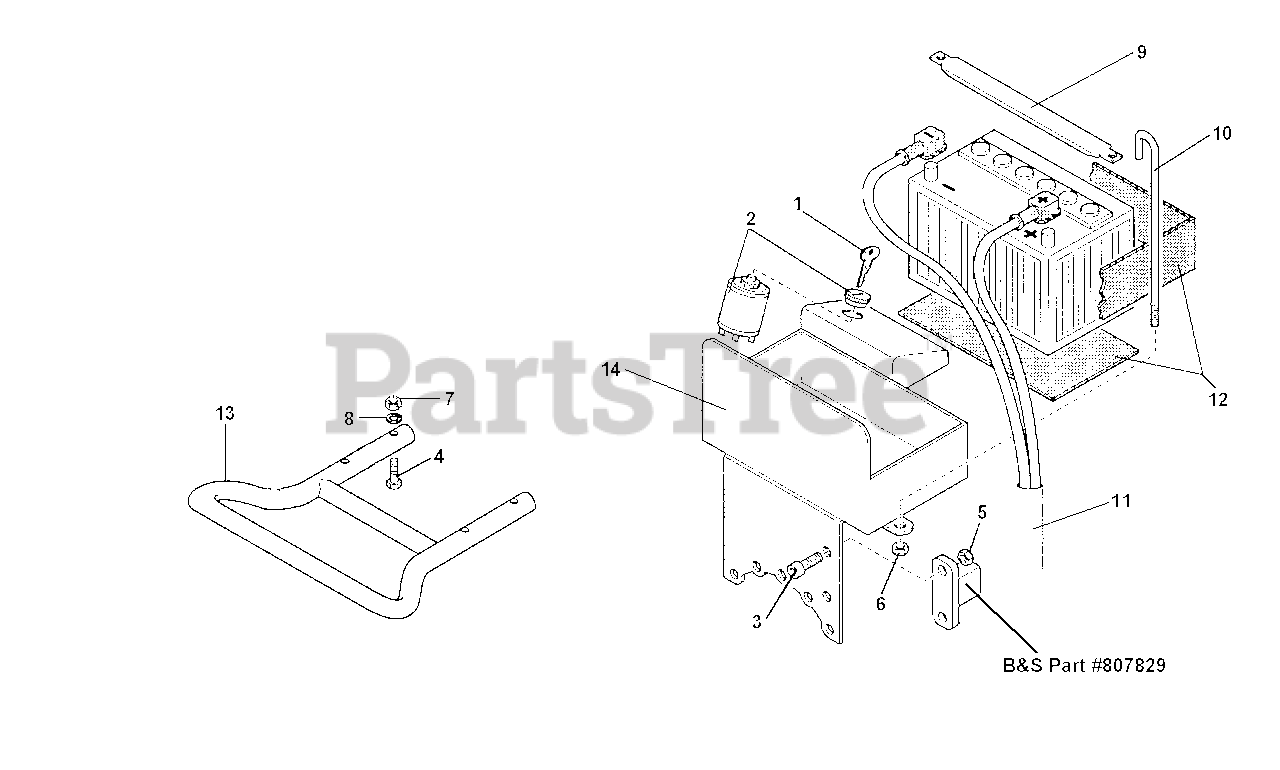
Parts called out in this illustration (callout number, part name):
3	SCREW M6X10
4	SCREW M8X60 9HP B&S
6	NUT, SELF LOCKING M6
7	NUT, SELF LOCKING M8
8	WASHER, LOCK 8.4
9	BATTERY BRACKET
10	BATTERY TIEROD
11	ELECTRIC STARTER CABLES, 9HP VANGUARD
12	BATTERY PADS
13	BUMPER, 9HP B&S
14	BATTERY SUPPORT
